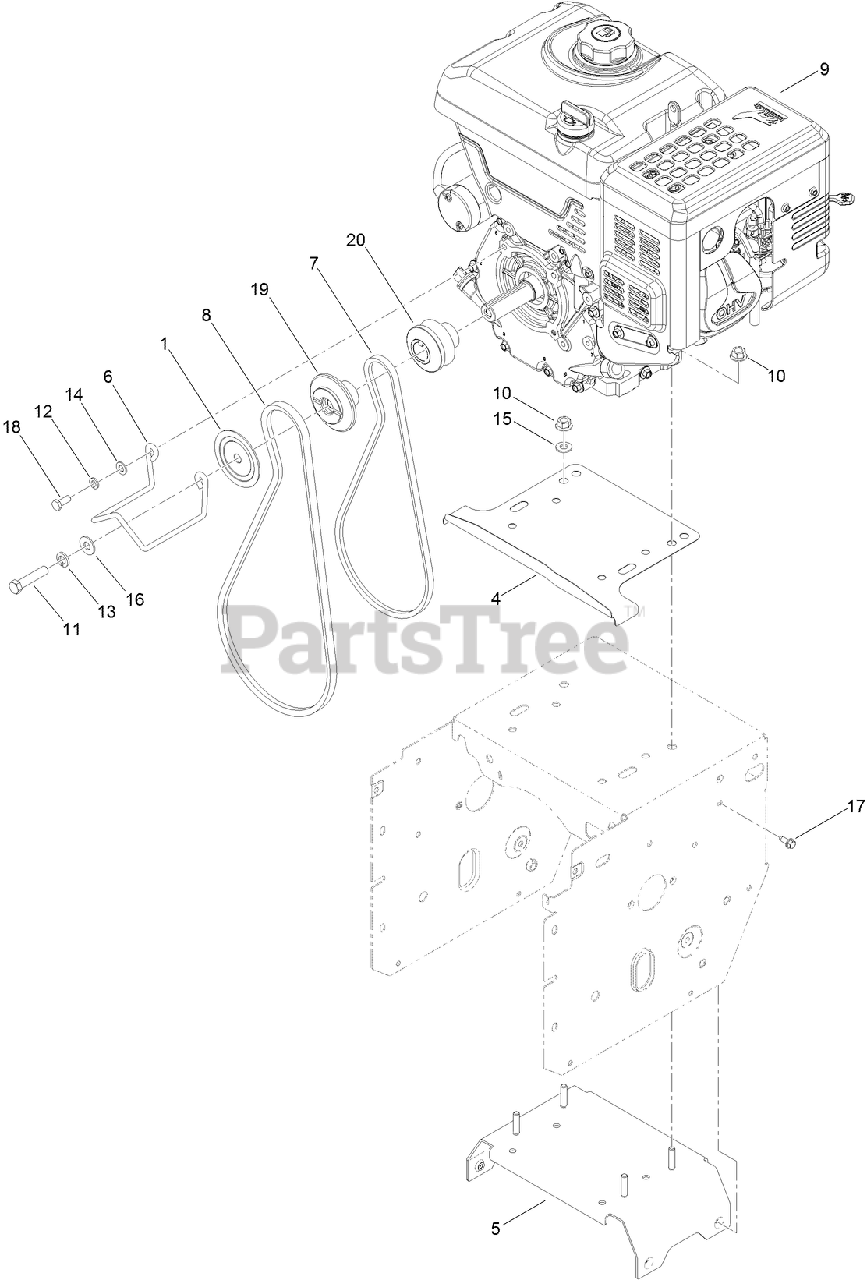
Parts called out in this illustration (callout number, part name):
1	SHEAVE-HALF, IMPELLER
4	SHIELD-DRIVE
5	FRAME BRACE ASM
7	BELT-V
8	BELT-V
9	ENGINE-180FDS-1
10	NUT-FLANGE
11	SCREW-HH
12	WASHER-LOCK
13	WASHER-LOCK
14	WASHER-PLAIN
15	WASHER-FLAT
16	WASHER-FLAT
17	SCREW-HWH
18	SCREW-HH
19	PULLEY-ENGINE, IMPELLER
20	PULLEY-TRACTION
